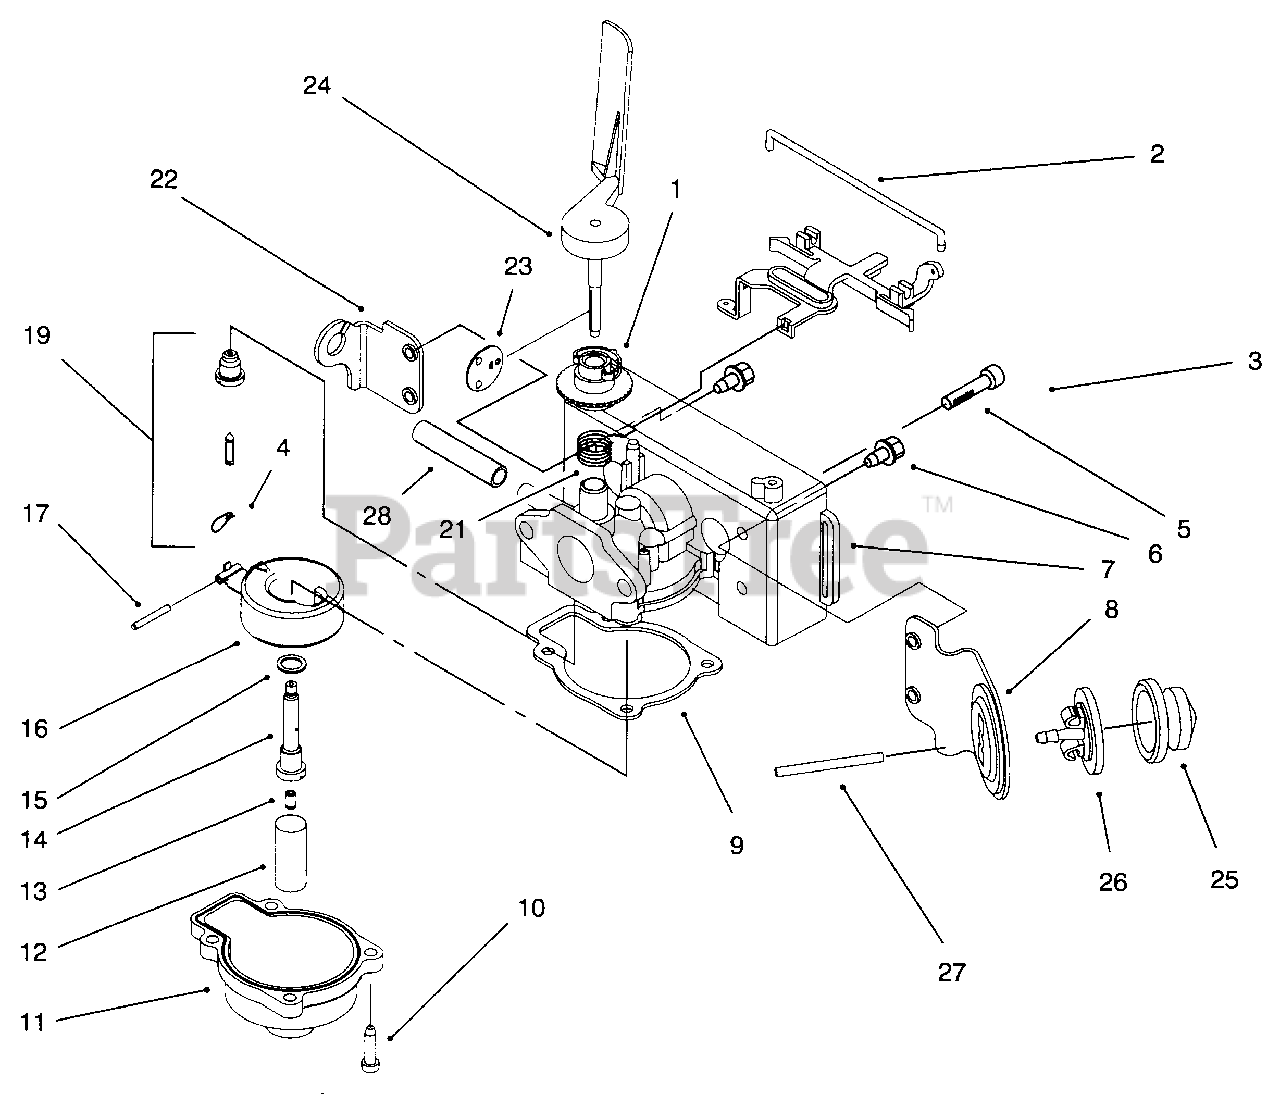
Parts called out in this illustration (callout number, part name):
1	Collar-Adjustment
2	Retainer
3	Lever-Speed Adjust
4	Spring
5	Screw-Pan Hd. Sems
7	Body-Carburetor
8	Bracket-Primer
9	Gasket-Float Chamber
11	Float Chamber
12	Filter-Fuel
13	Main Jet
16	Float & Arm Assembly
19	Float, Valve, & Body Ass'y (Incl. Ref. #4)
21	Spring-Governor
22	Bracket-Throttle Control
23	Disc-Throttle
24	Air Vane & Shaft
25	Bulb-Primer
26	Body-Primer
27	Hose-Primer
28	Line-Gas
